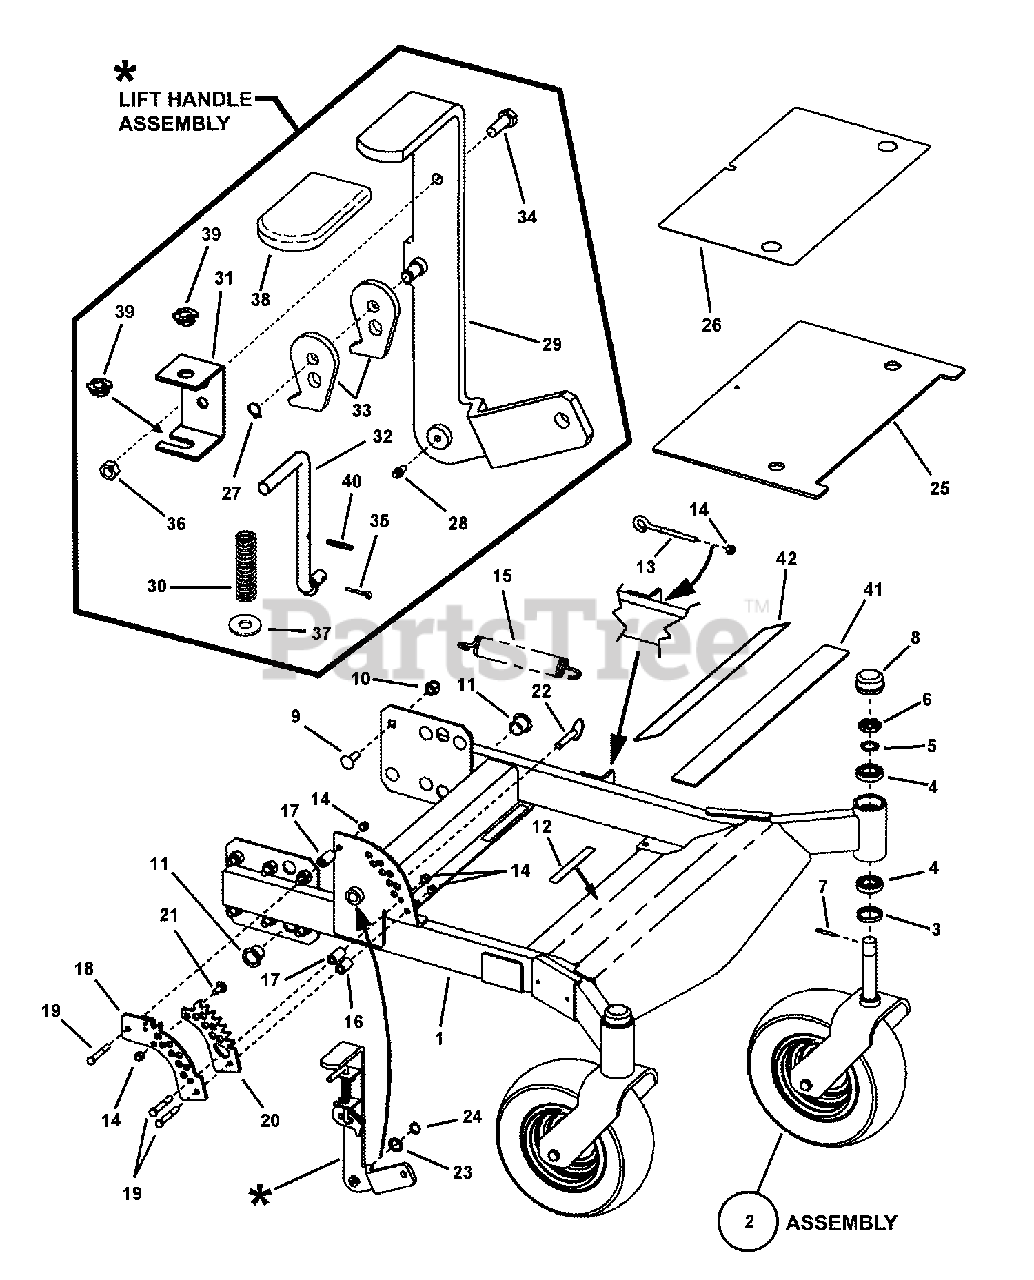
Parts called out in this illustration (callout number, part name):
1	WELDMENT, Front Frame
2	GROUP, Front Wheel (ref: Caster Wheel Assembly Page)
3	GREASE SEAL
4	BEARING, Tapered Roller
5	SPACER, Jackstaff
6	CASTLE NUT, 1-1/ UNF, GR B
7	ROLL PIN, 3/16 x 1-1/2"
8	CAP, Dust
9	BOLT, 1/2-13 x 1-1/2" Square Neck Carriage
10	NUT, 1/2-13 Hex Nyloc
11	BUSHING, Teflon
12	PAD, Floor Pan
13	EYEBOLT, 3/8-16 x 3"
14	NUT, 3/8-16 HEX NYLON LOCK
15	SPRING, Extension, Lift Assist
16	SPACER, Lift Adjust (1.08" Long)
17	SPACER, Lift Adjust (1.43" Long)
18	WELDMENT, Height Adjust
19	BOLT, 3/8-16 X 2-1/2" GD5 CZ
20	BRACKET, Deck Lift Detent
21	BOLT, 3/8-16 x 1" Square Neck Carriage GR 5
22	CLIP, Roll Pin, 1/2"
23	WASHER, .77 I.D. Flat
24	RING, 3/4" External Retaining
25	FLOOR PAN (Detached)
26	MAT, Floor Pan
27	RING, .375" Diameter External Retaining
28	LUBE FITTING, 3/16"
29	WELDMENT, Deck Lift Handle
30	SPRING, Neutral Return
31	BRACKET, Handle Support
32	ROD, Latch
33	STOP, Latch
34	SCREW, 5/16-18 x 1" Hex Head Cap, GR 5
35	PIN, 3/32 x 1/2" Cotter
36	NUT, 5/16-18 Hex Center Lock
37	WASHER, 3/8" Flat SAE
38	COVER, Plastic
39	BUSHING, 3/8" Plastic
40	ROLLPIN,1/8 x 7/8"
41	MAT, Footpan
42	MAT, Footpan
